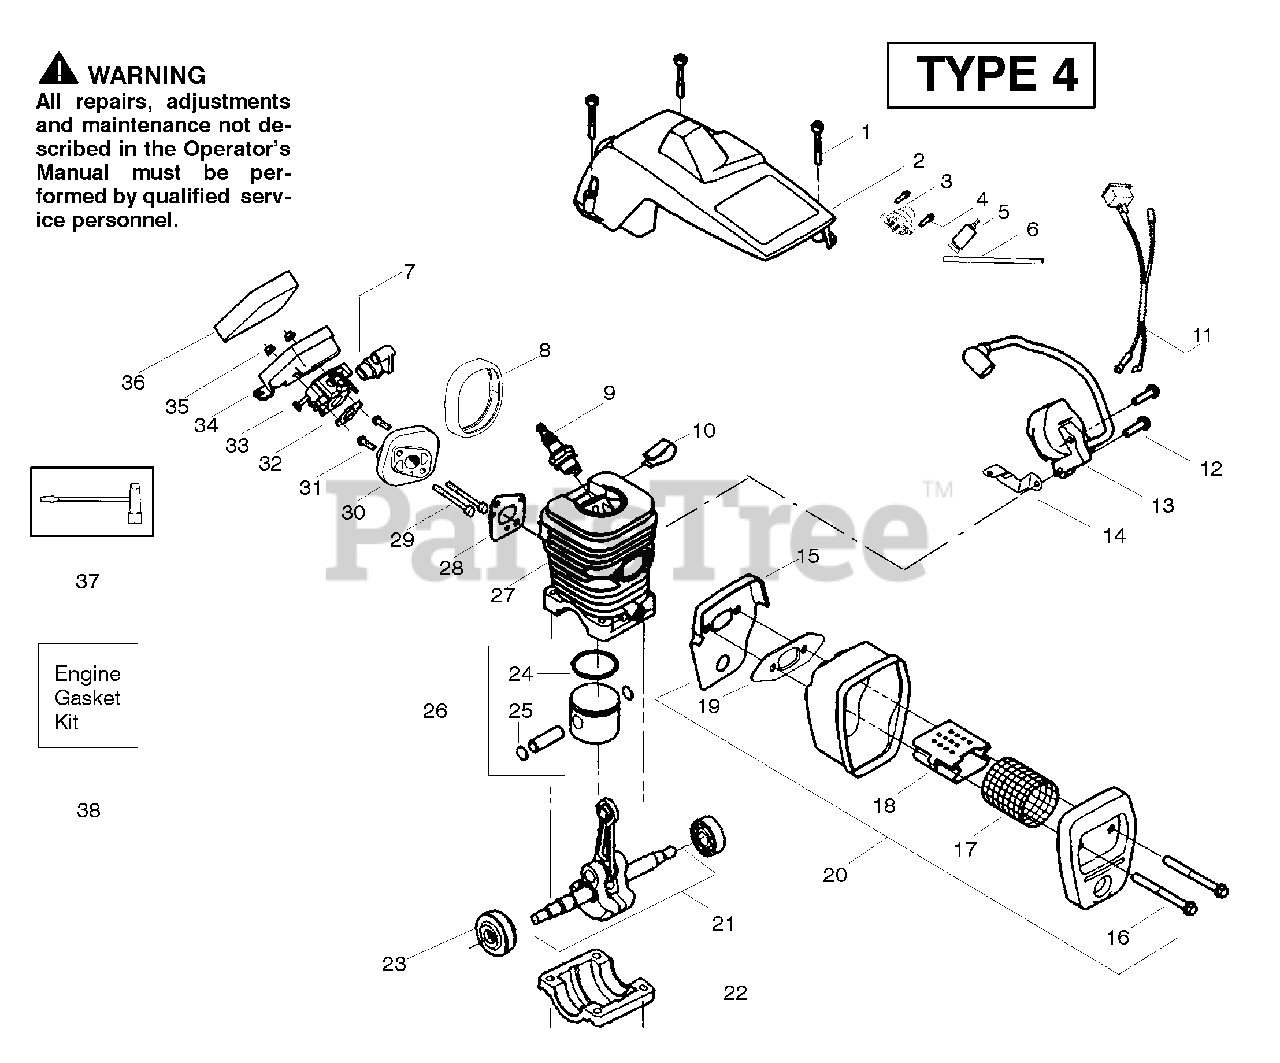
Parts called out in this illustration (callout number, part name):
2	Shield-Cylinder
3	Assy-Air Purge
5	Assy-Fuel Pick-up
6	Kit-Line Purge/Carb. (Small Dia)
7	Grommet-Carb Adjust.
8	Seal-Carb Adapter
9	Spark Plug (RCJ-7Y)
10	Clip-High Tension Lead
11	Assy-Wire Harness
13	Module-Ignition
14	Strap-Ground
15	Plate-Muffler Back
17	Screen-Spark
18	Muffler Diffuser
19	Muffler Gasket
20	Muffler Ass'y.
21	Assy-Crankshaft
22	Cap-Crankcase
23	Assy-Seal & Bearing
24	Ring-Piston
25	Retainer - Piston Pin
26	Kit-Piston
27	Cylinder
28	Gasket - Carb. Adapter
30	Adapter-Carb.
32	Carb. Gasket
33	Kit-Carburetor (WT-625)
34	Housing-Air Filter
36	Air Filter - Foam
37	Scrench
38	Kit-Engine Gasket
